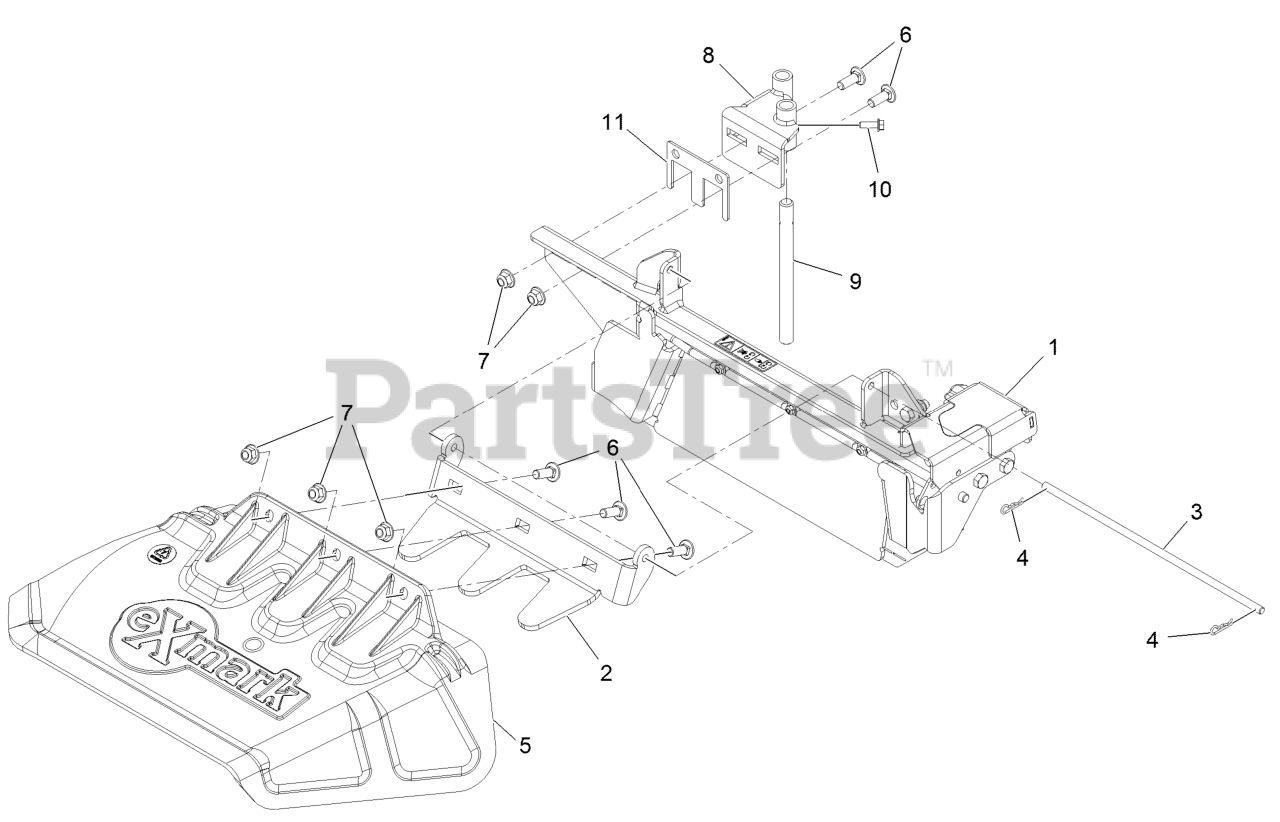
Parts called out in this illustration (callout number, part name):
1	ASM, OCD GATE
2	Mount-Discharge Chute
3	PIN,CHUTE
4	PIN-COTTER
5	CHUTE,DISCHARGE
6	SCREW-CARR
7	NUT-HF, NI
8	Ocd Mount ASM
9	PIN-MOUNT, OCD
10	SCREW-HHF
11	Shim-Ocdwb
